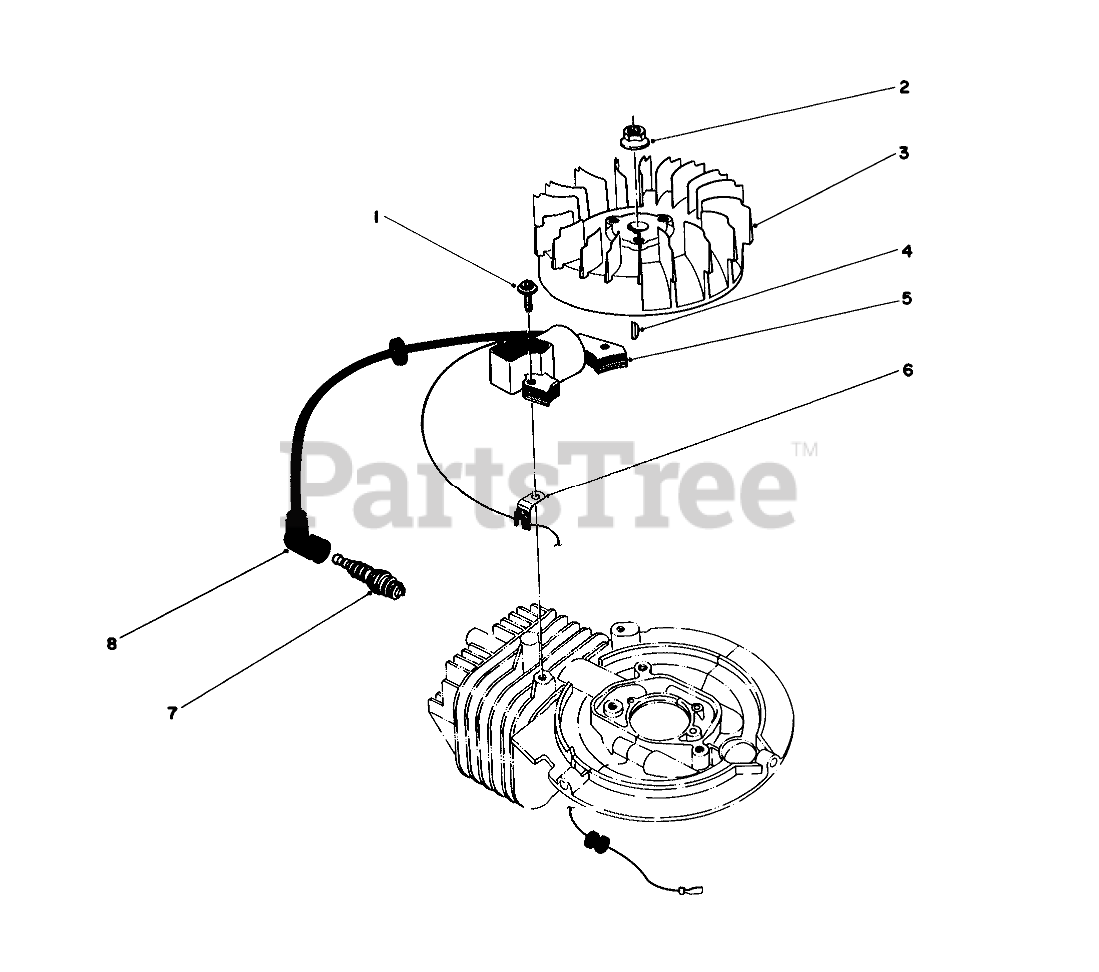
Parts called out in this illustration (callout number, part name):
1	Allenhead
3	FLYWHEEL
4	Key-Flywheel
5	Coil/Ignition Assembly
6	CLAMP
7	Sparkplug
8	CAP-SPARKPLUG
